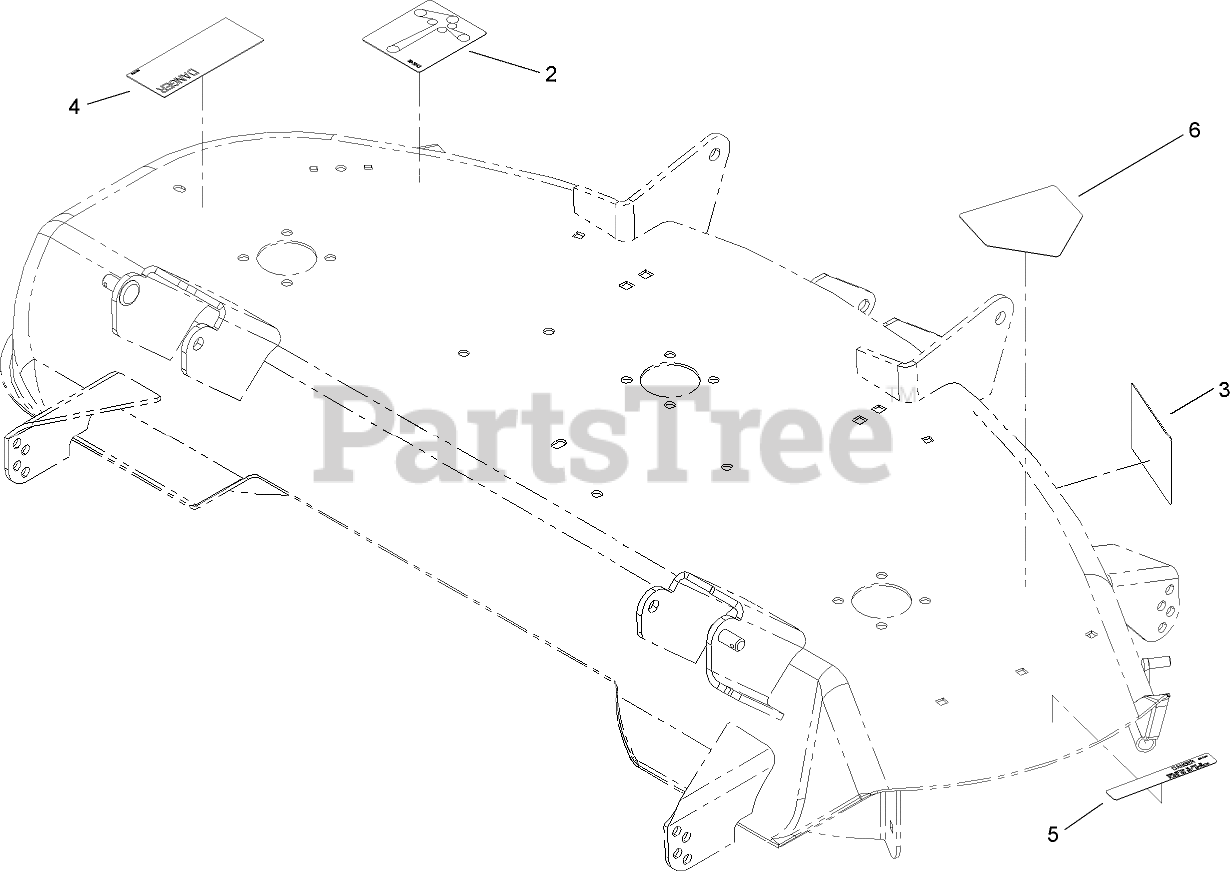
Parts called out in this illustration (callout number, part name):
2	DECAL-ROUTING, BELT
3	DECAL-WHEEL, GAGE
4	DECAL-DANGER
5	DECAL-CAUTION
6	DECAL-DANGER
